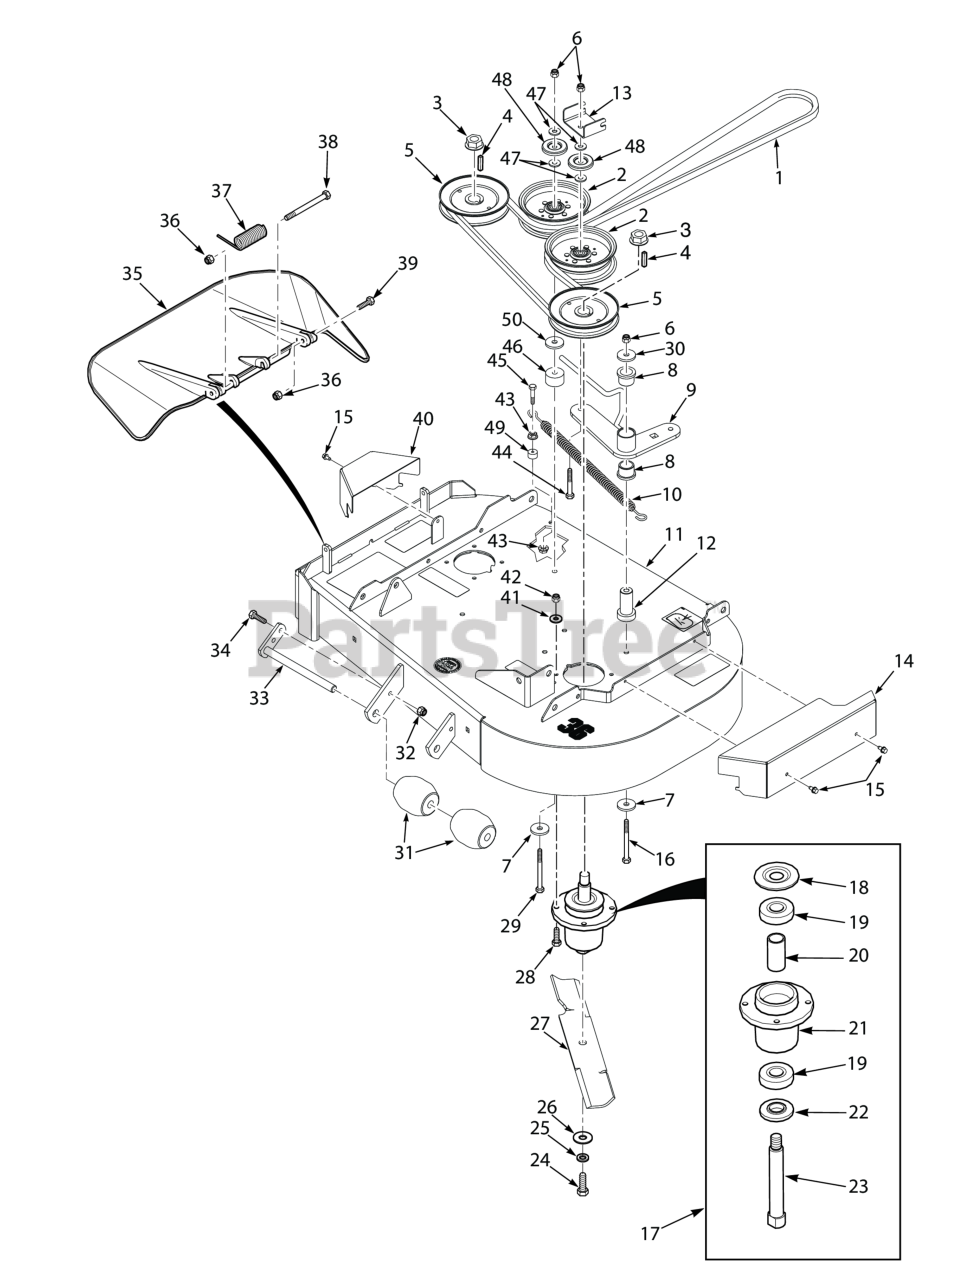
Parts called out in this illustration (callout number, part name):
1	Belt, Cutter Deck
2	Pulley, 5" Idler
3	Nut, 3/4-16 Spriral Lock
4	Key, 1/4 x 1/4 x 1.25" Pulley Mtg.
5	Pulley, 5.73" OD - 25mm Bore
6	HEX NUT, ELASTIC STOP LOCK, 3/8-16
7	Flatwasher, 3/8-.406 x 2.25" x .1875
8	Bearing, Plastic
9	Pivot, Idler
10	Spring, Cutter Deck Idler
11	Cutter Deck w/Decals, SMLZ-36
12	Pivot, Idler
13	Bracket, Belt Guide
14	Belt Cover LH SMZL-36
15	Screw, 1/4-20 x .375"
16	Bolt, Hex Head 3/8-16 x 4.00
17	Spindle Assembly
18	Debris Shield
19	Bearing
20	Spacer, Bearing
21	Spindle Housing Assembly
22	Protector, Bearing
23	Shaft, Spindle
24	Bolt, Hex Head 5/8-11 x 1-1/2"
25	Lockwasher, 5/8" Spring
26	Flatwasher, 5/8-.688 x 1-3/4 x .134 HD
27	Cutter Blade, 18" (52V)
28	Bolt, Hex Head 5/16-18 x 1-1/2" Grade 8
29	Bolt, Hex Head, 3/8-16 x 3-1/2"
30	Flatwasher, 3/8-.406 x 1-1-1/2 x 7 Gauge
31	Wheel, Anti-Scalp
32	Nut, Flange Head Elastic Stop 5/16-18
33	Shaft Weldment, Guide Roller
34	Bolt, Heax Head 5/16-18 x 1" (48V / 52V)
35	Discharge Chute Assy. SFZ48
36	HEX NUT, ELASTIC STOP LOCK, 5/16-18
37	Spring, Discharge Chute
38	Bolt, 5/16-18 x 4-3/4" Hex Head
39	Bolt, Hex Head 5/16-18 x 1-1/2" - Front
40	Belt Cover, RH SMZL-36
41	Lockwasher, 5/16 (.317 x .586 x .078) Helical Spring
42	Lock Nut, 5/16-18 Elastic Stop Grade 8
43	NUT, 3/8-16 SERRATED FLANGE HEX HEAD
44	Capscrew, Hex Head 3/8-16 x 2-1/2"
45	Bolt, Hex Head 3/8-16 x 1-1/2" Grade 8 Black
46	Spacer, Idler Pulley
47	Flatwasher, 3/8 (.391 x .938 x .105 HD) Grade 8
48	Quick Pin, 5/16" Dia.
49	SPACER, IDLER
50	Flat washer, 1/4-.266 x .875 x .125
